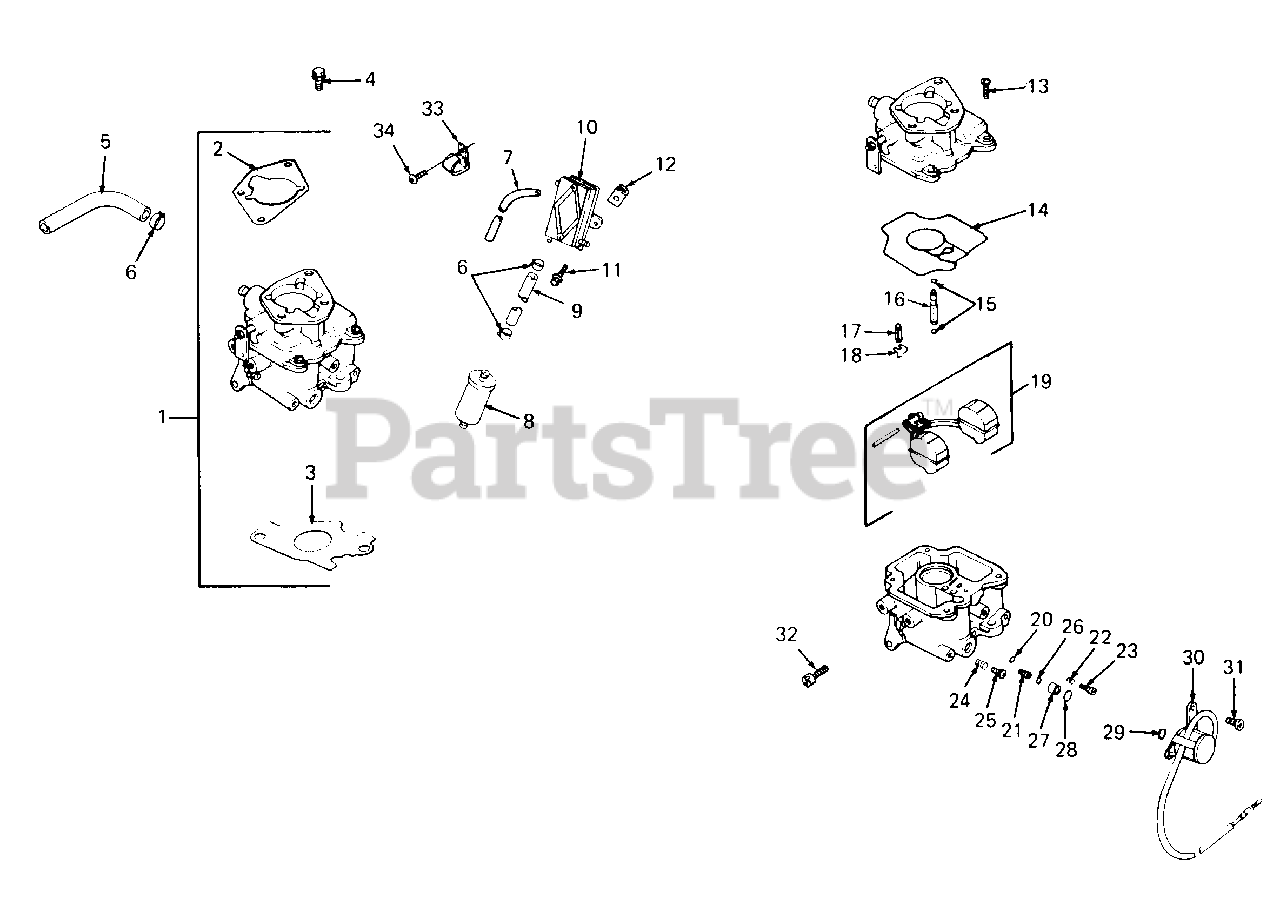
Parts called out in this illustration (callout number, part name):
1	Kit, Carburetor
2	Gasket, Air Cleaner
3	Gasket, Carburetor
4	Screw, M6 x 1.0 x 18
5	Line, Fuel, 9
6	Clamp, Hose
7	Line, Fuel, 15.5
8	Filter, Fuel
9	Line, Fuel, 10
10	Pump, Fuel-Pulse
11	Screw, Hex Cap
12	Nut
13	Screw, Carburetor Body
14	Gasket, Carburetor Body
15	O-Ring, Slow Jet
17	Valve, Inlet Needle
18	Clip, Inlet Needle Valve
19	Kit, Float Repair
20	O-Ring, Main Jet
22	Spring, Idle Adjust
23	Needle, Idle Adjust
24	Spring, Idle Speed Adjust 1
25	Screw, Idle Speed Adjust 1
27	Seat, Solenoid
29	O-Ring, Solenoid
30	Solenoid
32	Screw, Throttle Stop
33	Clip, Cable
34	Screw, M6 x 1.0 x 10
